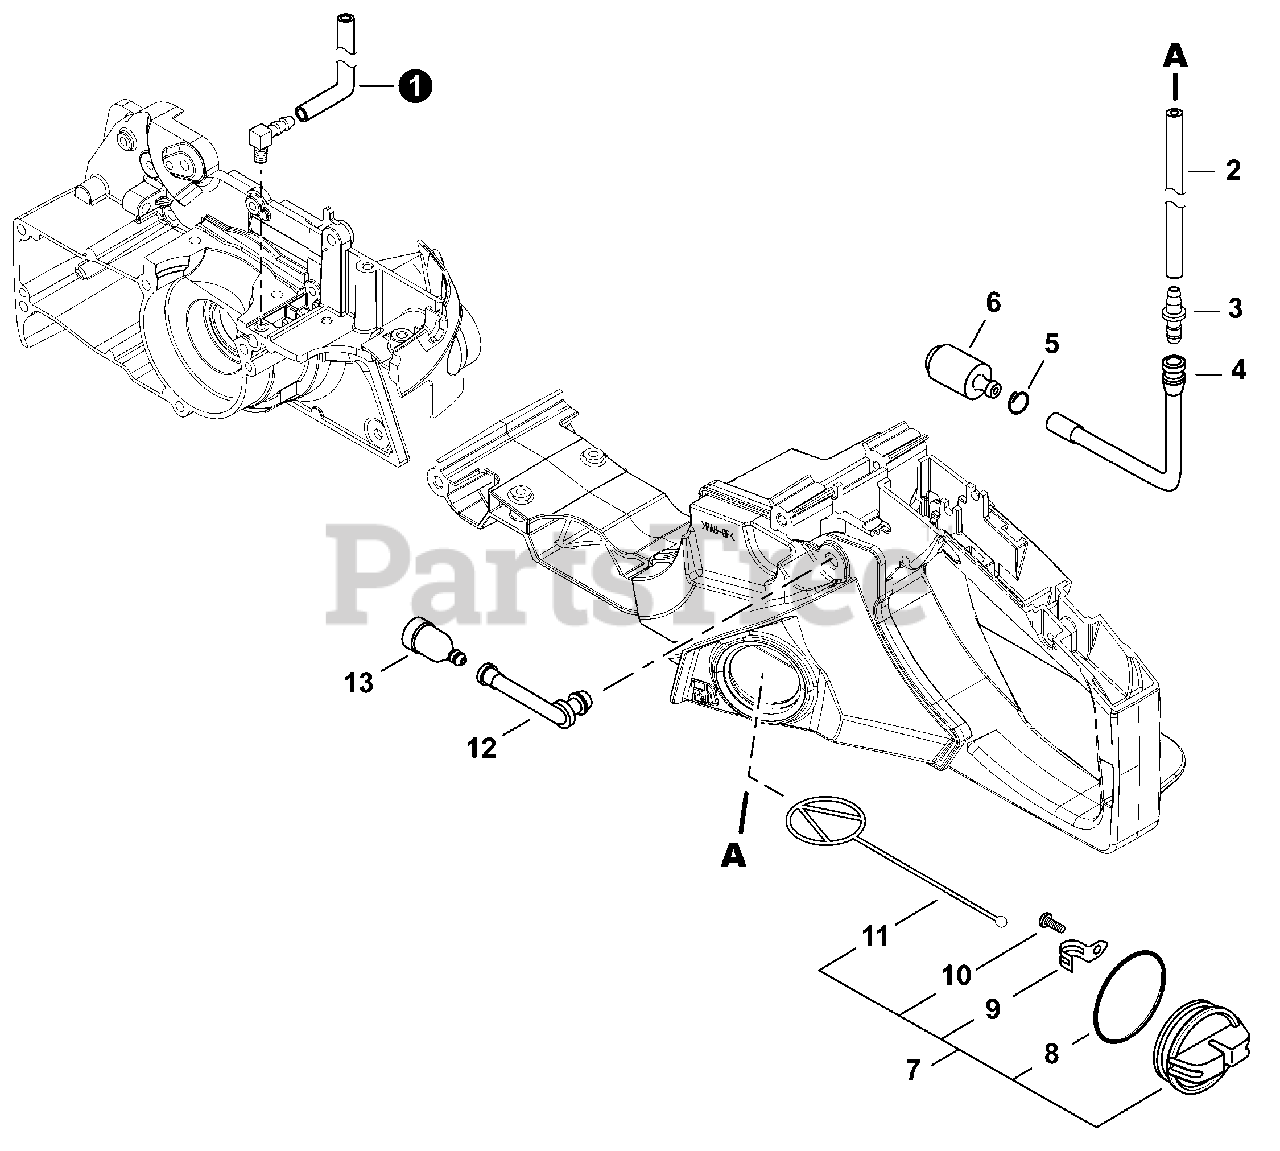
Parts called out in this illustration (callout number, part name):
1	PIPE, PULSE
2	PIPE, FUEL 3×6×75
3	CONNECTOR, PIPE
4	PIPE, FUEL
5	CLIP Ø6
6	FILTER, FUEL
7	CAP ASSY, FUEL
8	O-RING 29
9	RETAINER, CONNECTOR
10	SCREW, TAPPING 3×8
11	CONNECTOR, CAP L= 60 MM
12	PIPE, FUEL VENT
13	VENT ASSY
